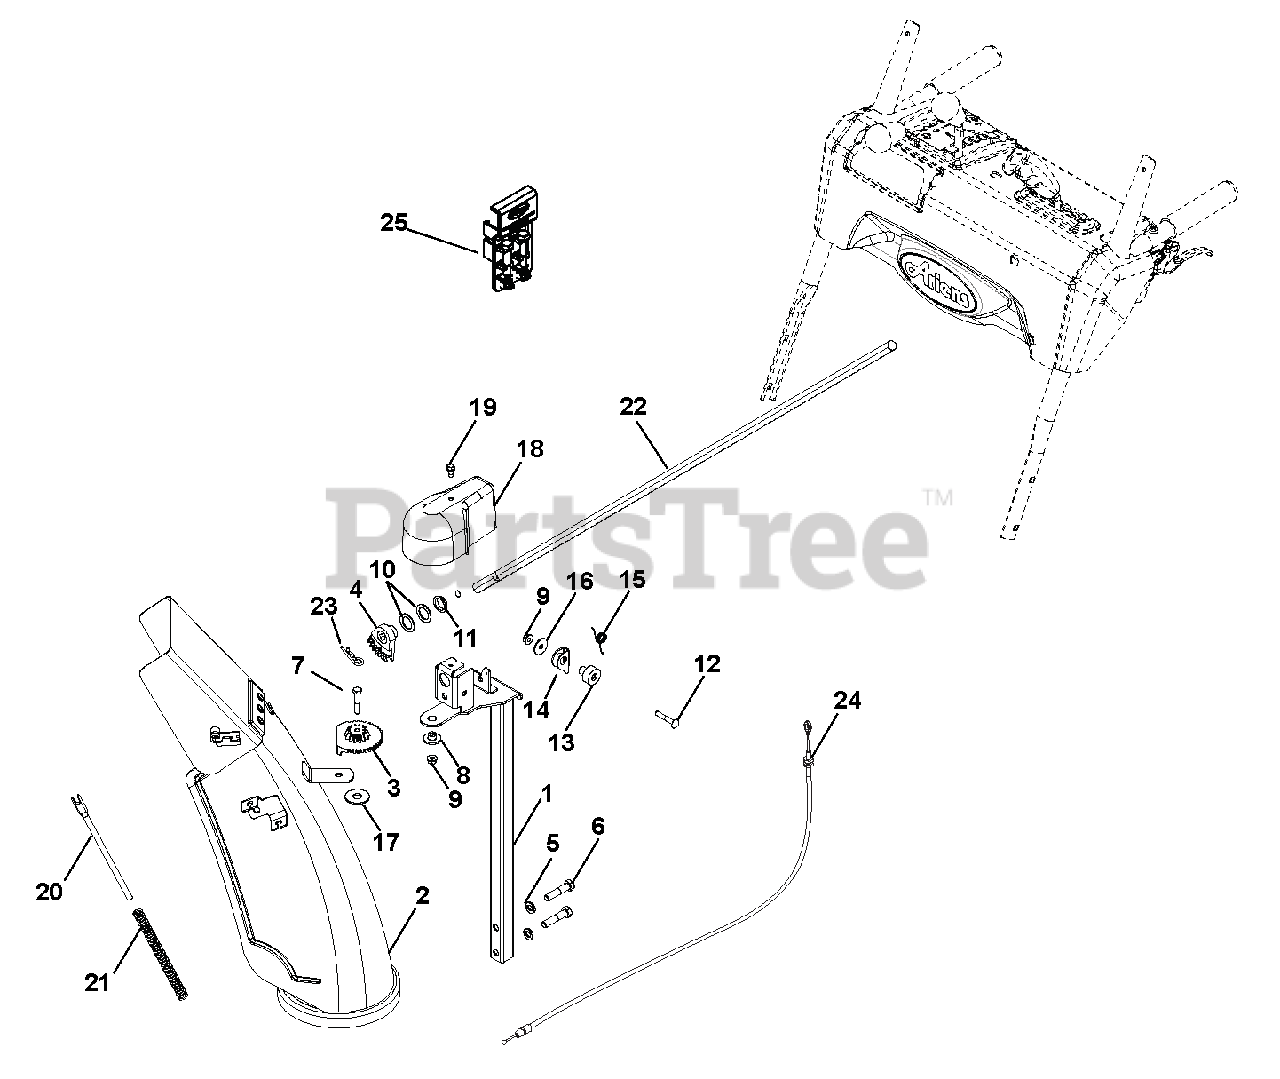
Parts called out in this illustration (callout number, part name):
1	PEDESTAL, CHUTE - QUICK STICK
2	CHUTE, DISCHARGE-W/DEFLECTOR
3	GEAR, CHUTE
4	GEAR, CHUTE-ACTUATION
5	@WSHR-LK .38X.094 REG YWZC
6	@BLT-HEX .38-16X1.75 GR5 YWZC
7	@BLT-HEX .25-20X1.50 GR5 YWZC
8	BSHG-FLG .265X.477X.375X1.00
9	@NUT-LK-TOP-FLG .25-20 YWZC
10	WSHR-FL-STL.754X1.125X.062YWZC
11	BUSHING, POLYLINER-.75 SNAPIN
12	@BLT-RDHDSQNK .25-20X1.50 G5YZ
13	BUSHING, LOCK ARM
14	ARM, LOCKING
15	SG-TORS
16	WSHR-FL-STL .281X1.000X.063
17	WSHR-FLT-NYL .515X1.375X.093
18	COVER, CHUTE GEAR
19	SCR-TAP .25-20X.50 HWH TR YWZ
20	ROD, DEFLECTOR CAP
21	SG-COMP .08X.40X6.50 14#/IN
22	ROD, HEX - CHUTE ROTATION
23	PIN-HAIR INT .08X.18X1.18 YWZC
24	CABLE, DEFLECTOR-COATED
25	HOLDER W LARGE SHEAR BOLT /NUT
